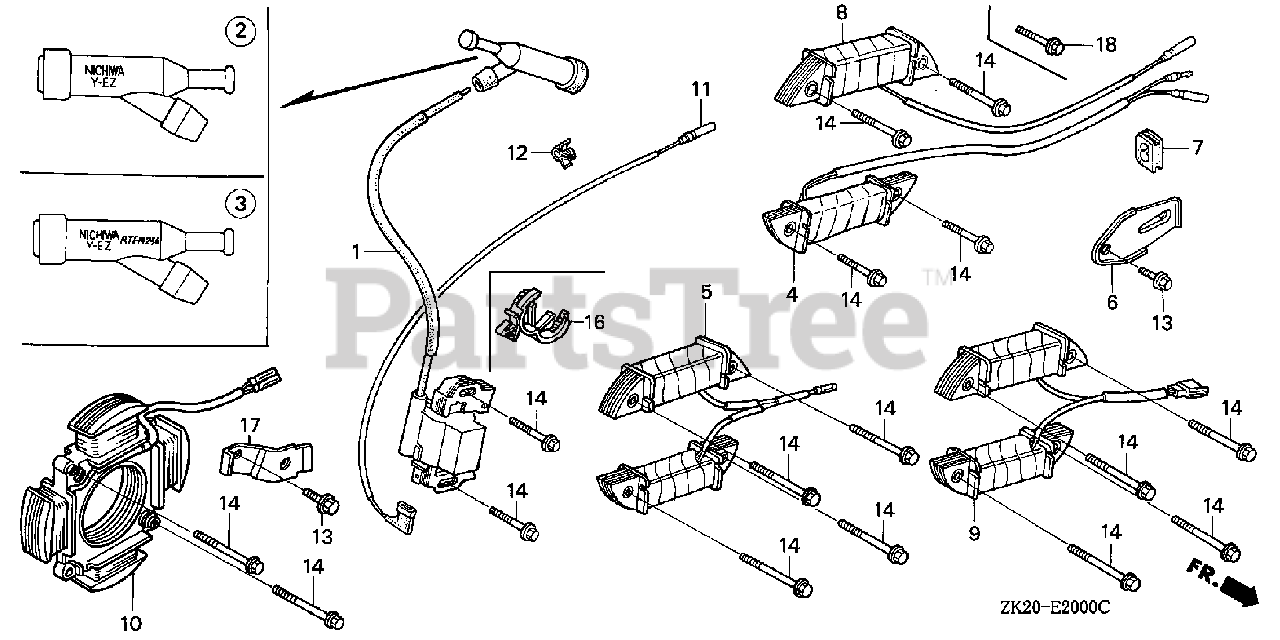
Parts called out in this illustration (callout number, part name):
1	COIL ASSY., IGNITION
3	CAP ASSY., NOISE SUPPRESSOR
7	GROMMET, WIRE
11	WIRE, STOP SWITCH (370MM)
14	BOLT, FLANGE (6X28)
16	CLIP, WIRE HARNESS
